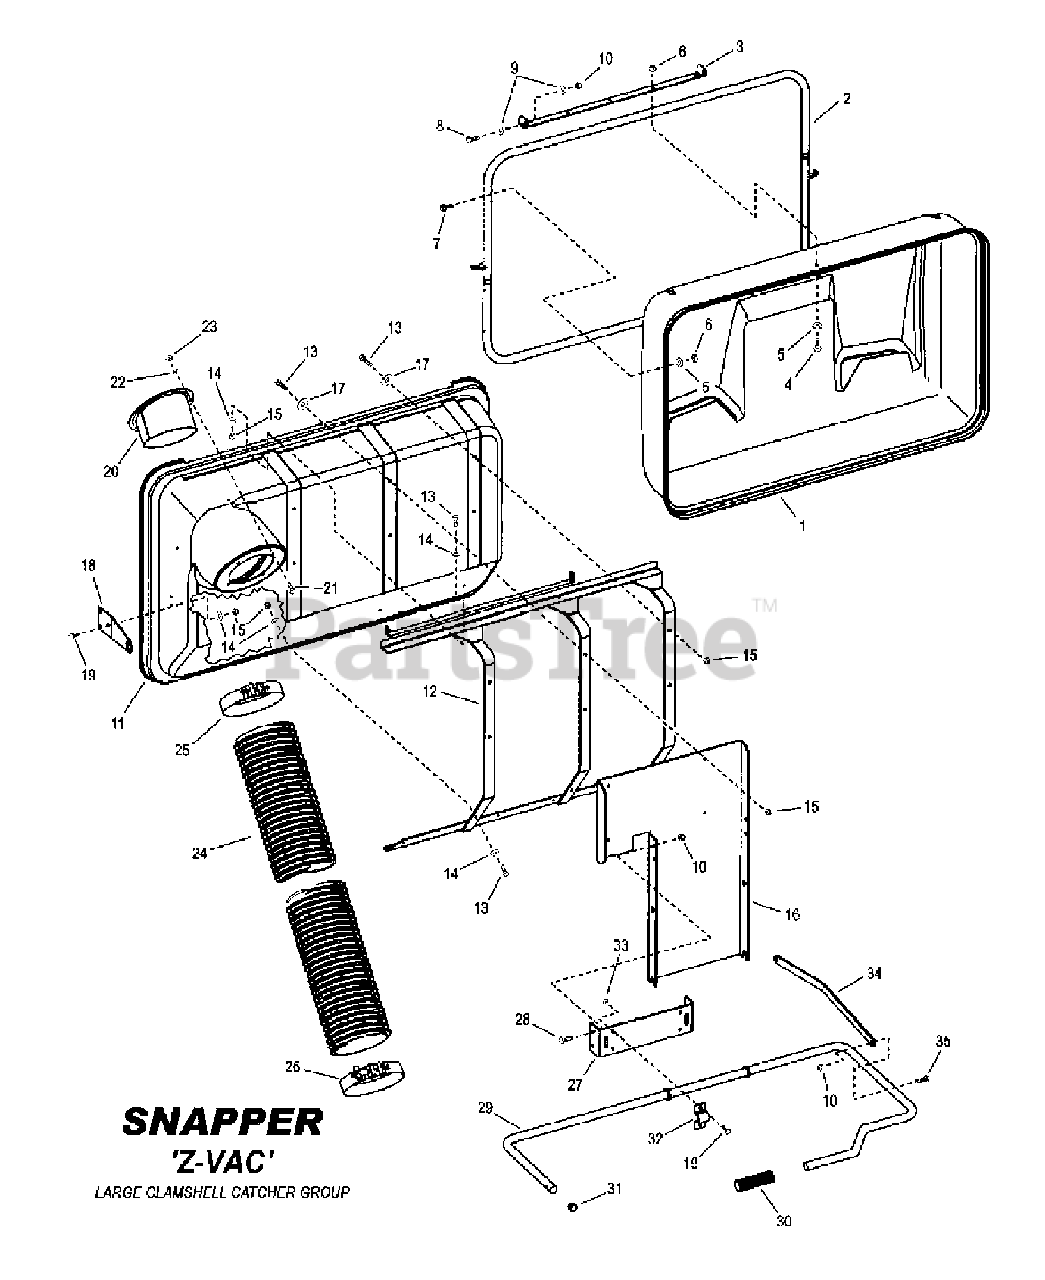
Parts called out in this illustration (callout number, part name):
1	COVER, Rear Clamshell Bagger, 14 CU FT
2	WELDMENT, Rear Cover Brace
3	HINGE, Rear Cover
4	SCREW, Hex Washer Head Machine, #17024 X 1-1/2 GR5
5	WASHER, Flat .190 I.D. X .75 O.D. YZ
6	NUT, Hex Flange Lock,, 17024
7	BOLT, Oval Head 17024
8	SCREW, Hex Head Cap 3/8-16 X 1 YZ
9	WASHER, SAE 3/8
10	NUT, Hex Lock, 3/8-16 Nylock YZ
11	FRONT COVER, Comm. Clamshell, 14 CU FT
12	WELDMENT, Mounting Brace, 14 CU FT Clamshell Front
13	SCREW, Hex Head Cap 5/16-18 X 1.25 GR 5 YZ
14	WASHER, Flange Lock .375 X .875 X .083 YZ
15	NUT, Hex Lock 5/16-18-3B YZ ESNA
16	MOUNT, Comm. Clamshell
17	WASHER, .33 ID X 1.25 X .09
18	BRACE, Handle,Clamshell
19	BOLT, Carriage Short Neck 5/16-18 X 1 GR 5 YZ
20	WELDMENT, Tube Adapter
21	SCREW, Hex Head Cap 1/4-20 X 1-1/4 YZ
22	WASHER, Split Lock .32 X .58 X .08 YZ
23	NUT, Hex 1/4-20 YZ
24	HOSE, SNAPPER Fast-Vac
25	CLAMP, Hose Upper
26	CLAMP, Hose Lower, Fast-Vac
27	BRACKET, Handle Mount, Clamshell
28	BOLT, Hex Flange Lock 3/8-16 X 1.0 -YZ
29	WELDMENT, Handle, Comm. Clamshell
30	GRIP
31	ENDCAP, Tube
32	BRACKET, Hanger, Deck Lift
33	NUT, Flange Lock,, 5/16-18 YZ
34	ARM, Clamshell Actuating
35	SCREW, Hex Head Cap 3/8-16 X 2 GR5 YZ
